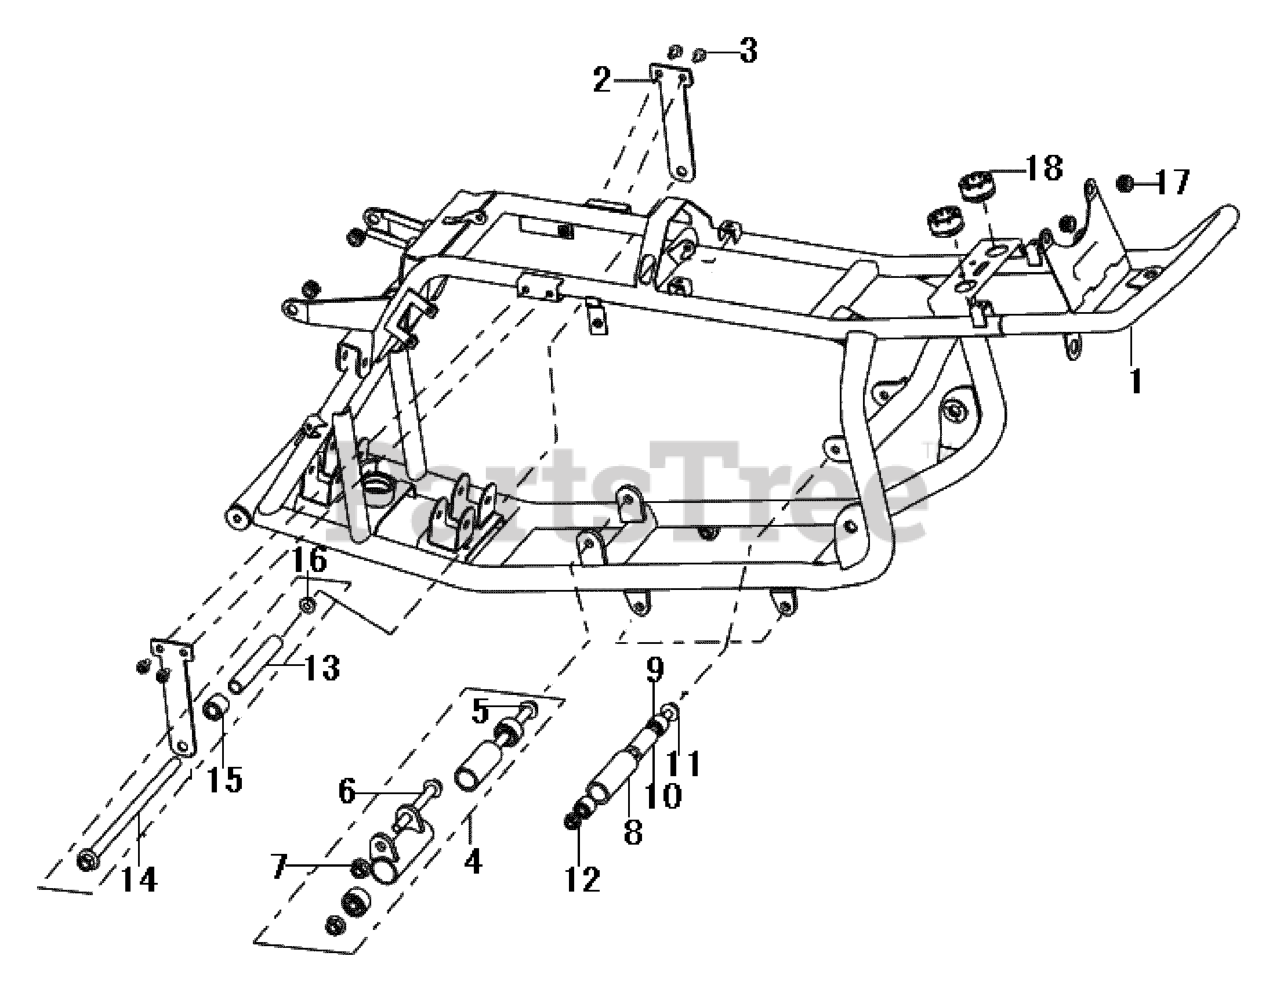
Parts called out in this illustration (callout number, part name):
1	FRAME ASSY.
2	BRACKET, SUPPORT
4	ENGINE MOUNT ASSY.
9	BUSHING
18	ABSORBER, RUBBER
